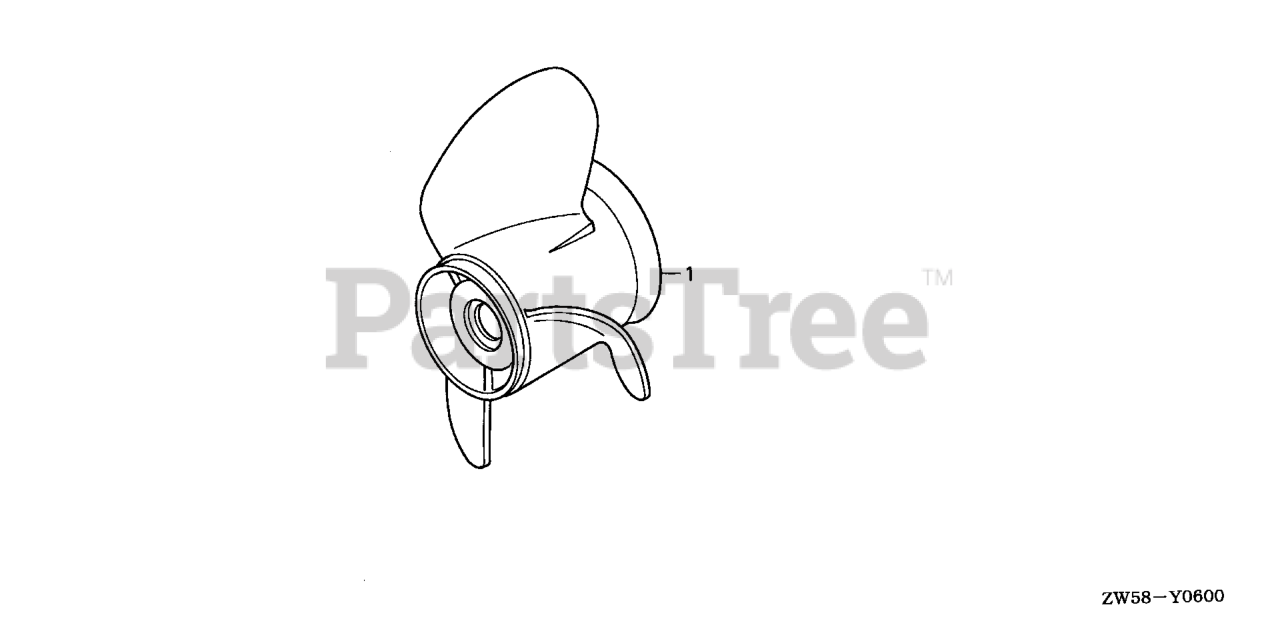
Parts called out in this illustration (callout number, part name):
1	PROPELLER, THREE-BLADE (13-1/4X17) (SUS/CR)
1	PROPELLER, THREE-BLADE (13-1/4X15) (SUS/CR)
1	PROPELLER, THREE-BLADE (13-1/4X19) (SUS/CR)
1	PROPELLER, THREE-BLADE (13-1/4X21) (SUS/CR)
